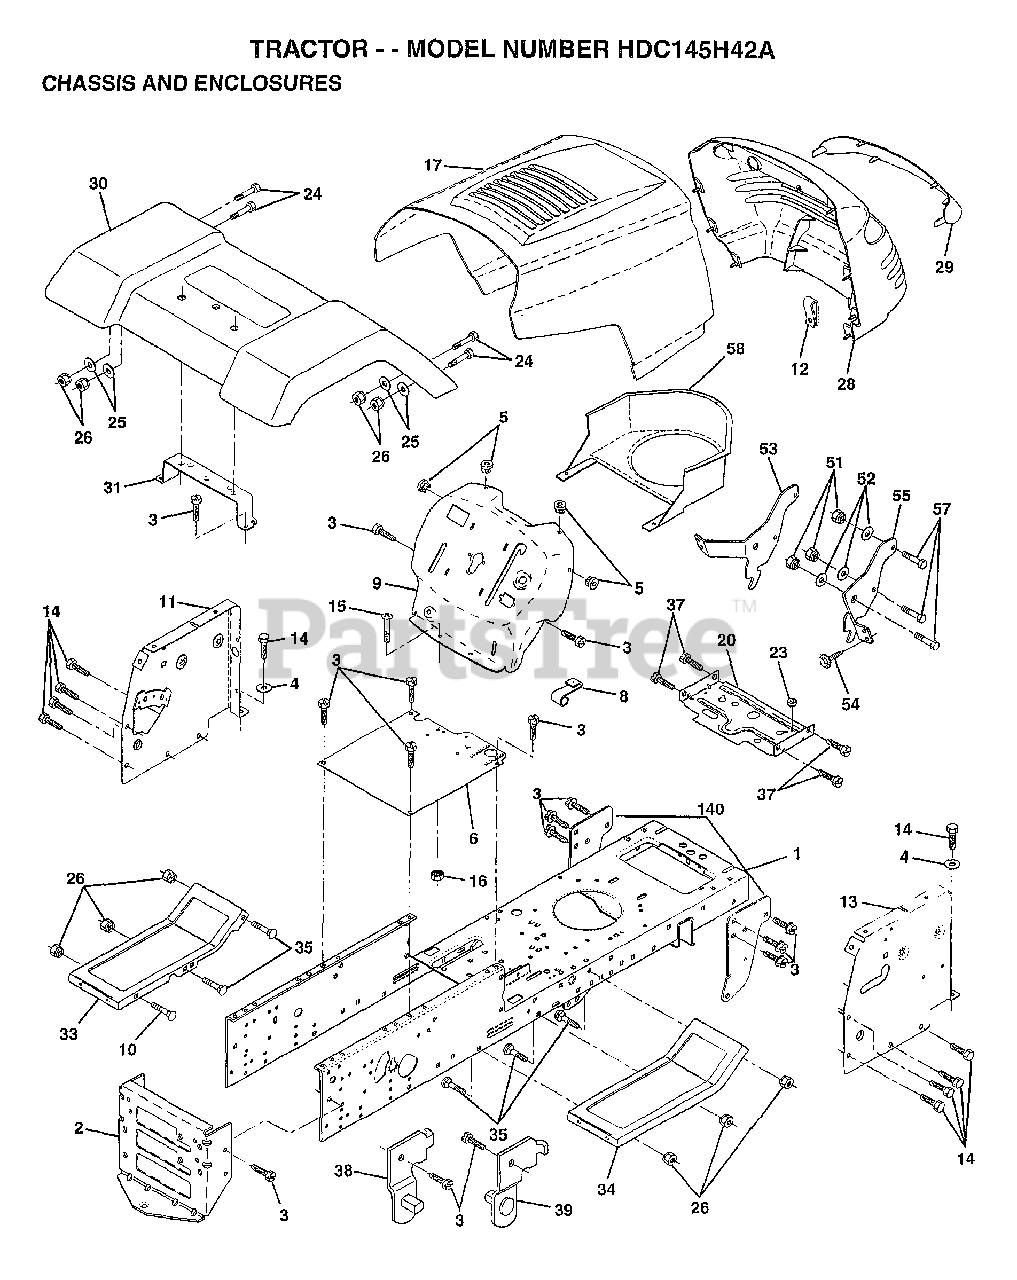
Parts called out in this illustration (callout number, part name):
1	CHASSIS ASM
3	SCREW
4	WASHER
5	BUMPER-HOOD/DASH
6	SADDLE
8	CLIP.RETAINER
9	DASH.SILKSCREENED
11	"PANEL-DASH,LH"
12	CLIP.TINNERMAN
14	SCREW LT
15	SCREW
20	"PLATE-MTG,BATT/FU"
24	BOLT
25	WASHER
26	NUT
28	GRILLE-MS428
29	LENS GRILLE
30	FENDER ASM LT W/S
31	BRKT FENDER
33	FOOTREST LH
34	FOOTREST RH
35	BOLT
37	SCREW LT
38	BRACKET ASM LH
39	BRACKET ASM RH
51	NUT
52	WASHER
53	BRACKET.GRILLE.LH
55	BRACKET.GRILLE.RH
58	AIR DUCT
140	BRKT SUSPENSION
